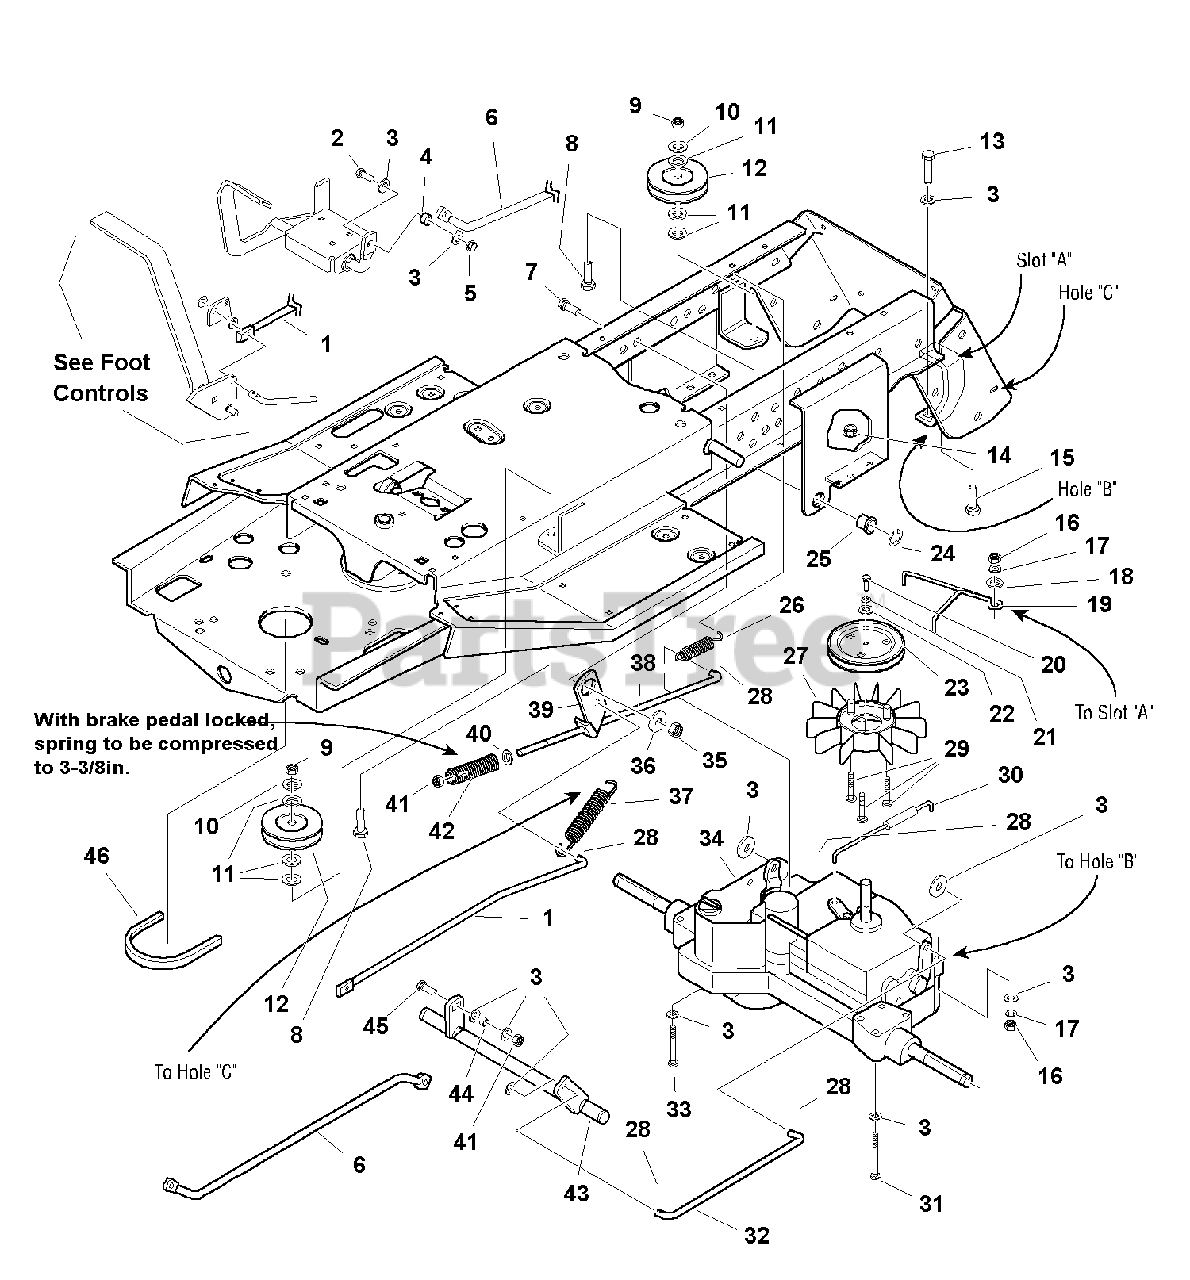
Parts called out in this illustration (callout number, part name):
1	ROD, Front Brake
2	CAPSCREW, Hex Head, 5/16-18 x 7/8
5	NUT, Hex Flange Two-Way Lock, 5/16-18
7	CAPSCREW, Hex Head, 3/8-16 x 1
8	CARRIAGE BOLT, 3/8-16 x 1-1/2
9	NUT, Hex, 3/8-16
10	LOCKWASHER, 3/8
11	WASHER, 3/8
13	CAPSCREW, Hex Head, 5/16-18 x 1-3/4
14	NUT, Hex Flange Two-Way Lock, 5/16-18
15	CARRIAGE BOLT, 5/16-18 x 1-1/4
16	NUT, Hex, 5/16-18
17	LOCKWASHER, 5/16
18	WASHER
19	GUIDE, Belt
20	CAPSCREW, Hex Head, M06-1.00 x 20MM 8.8
21	LOCKWASHER, 1/4
22	WASHER, 1/4
23	PULLEY & HUB ASSEMBLY
25	BUSHING, Nylon
26	SPRING, Extension
28	PIN, Cotter, 3/32 x 3/4
29	CAPSCREW, Hex Washer Head Taptite, 1/4-20 x 1-1/2
30	ROD, Dump Valve
31	CAPSCREW, Hex Head, 5/16-18 x 3
32	ROD, Transmission
33	CAPSCREW, Hex Head, 5/16-18 x 2-1/2
34	TRANSMISSION ASSEMBLY, Tuff Torq K51
35	NUT, Hex Lock ESNA Heavy, 3/8-16
37	SPRING, Extension
38	ROD, Rear Brake
39	ARM, Brake Pivot
40	WASHER
41	NUT, Hex Lock ESNA Light, 5/16-18
42	SPRING, Compression
43	SHAFT & ARMS ASSEMBLY
45	CARRIAGE BOLT, 5/16-18X1
